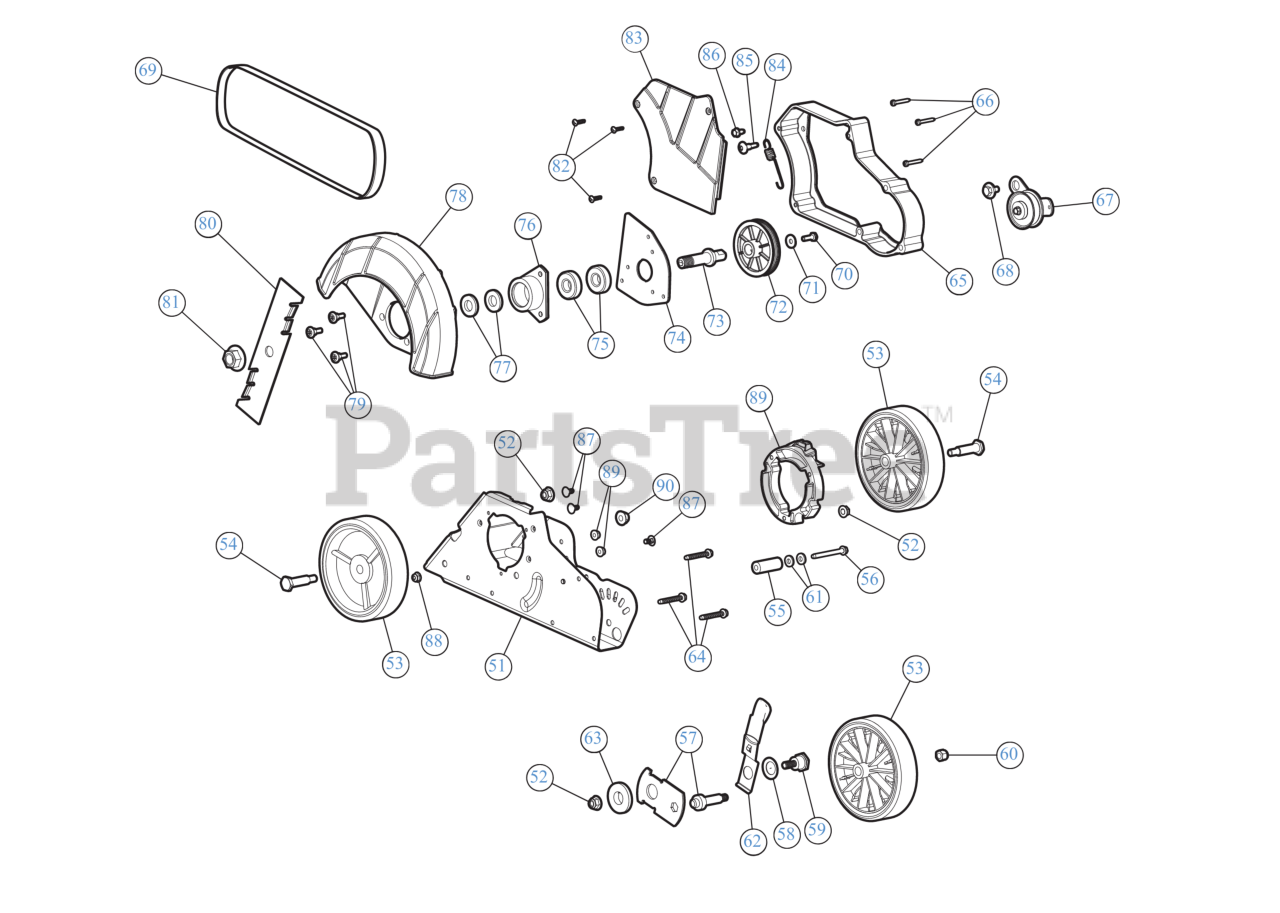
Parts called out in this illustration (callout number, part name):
51	EDGER FRAME
53	WHEEL 5-1.5 GRAY
54	SHOULDER SCREW
56	SCREW 1/4-20 x 2.375
58	BELL WASHER
59	SHOULDER SCREW .75 X.50 X3/8-16
60	HEX NUT INS L-3/8-16
62	HEIGHT LEVER ASSEMBLY
63	HEIGHT ADJUSTMENT BEARING
64	SCREW 1/4-20 x 1.750
66	SCREW 8-16X1.25
67	IDLER PULLEY ASSEMBLY
68	SHOULDER SCREW .560X.165: 5/16-18
70	SCREW 1/4-20X.75 GR5
71	SPRING WASHER BELL
73	BLADE SPINDLE
74	SPINDLE MOUNT PLATE
75	BALL BEARING
76	BEARING CUP
77	FLAT WASHER .635 x 1.24 x .181
78	EDGER BLADE GUARD (W/LABEL)
79	SHOULDER SCREW .375X.280:1/4-14
82	SCREW 8-16 x 3/4
83	BELT COVER
85	BOLT 1/4-20
86	SCREW 1/4-20 X.500
87	CARRIAGE BOLT 1/4-20X.50"
88	FLANGE LOCK NUT
